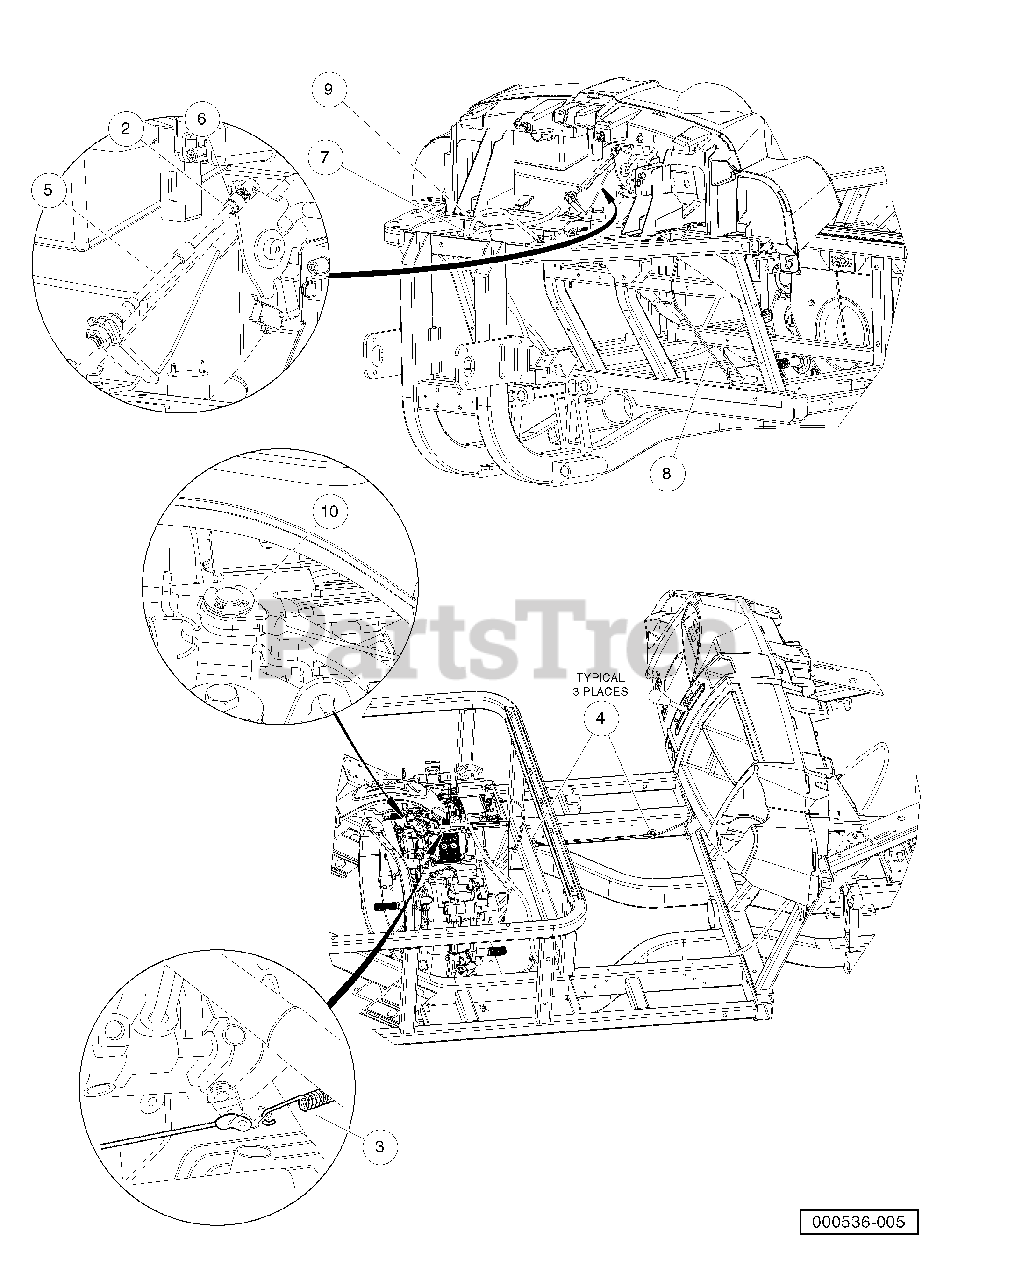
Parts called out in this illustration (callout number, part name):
1	Instl, Cable, Awd, Fh680d
2	Nut, 1/4-28 Hex Jam
4	Clip, Brake Line
5	Cable, Transmission Shift
6	Joint, Ball, .346 Dia
7	Cable, Accel, AWD, Gas, FH680D
8	Cable, Choke, AWD, FH680D
9	Tie Wrap, 8" Nylon
10	Ring, Retaining
